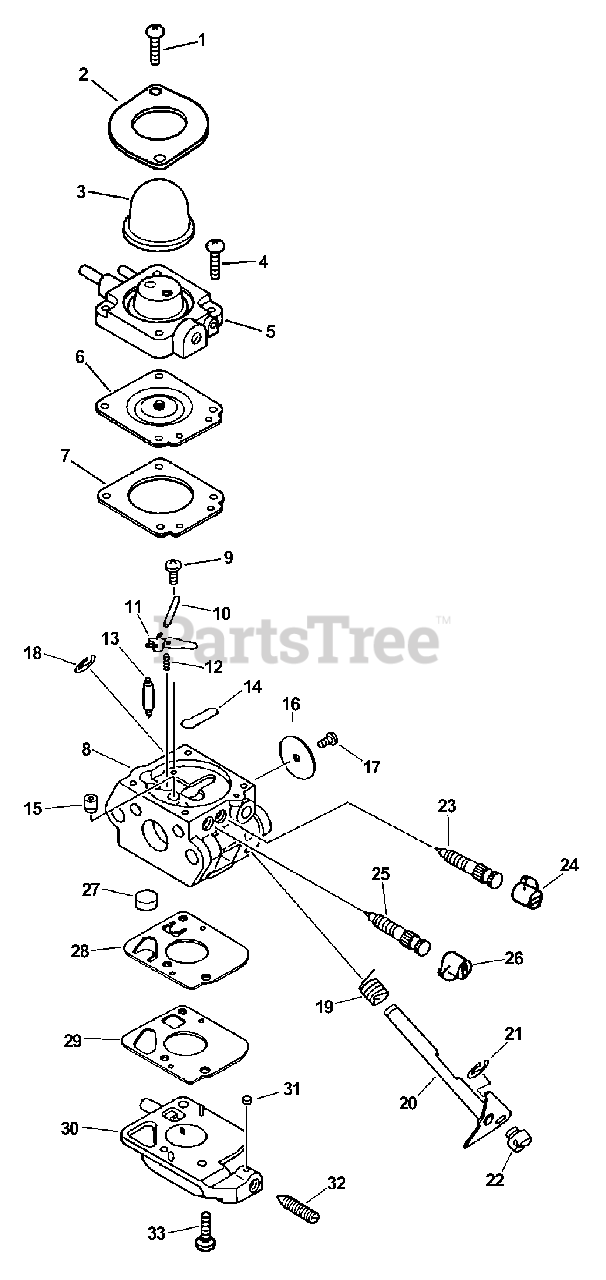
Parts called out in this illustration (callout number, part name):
1	SCREW, RETAINER
2	RETAINER, PURGE BULB
3	BULB, PURGE
4	SCREW, PURGE BASE
5	BASE, PURGE
6	DIAPHRAGM, METERING
7	GASKET, METERING
8	BODY, CARBURETOR
9	SCREW, METERING LEVER PIN
10	PIN, METERING LEVER
11	LEVER, METERING
12	SPRING, METERING LEVER
13	VALVE, INLET NEEDLE
14	PLUG, WELCH
15	NOZZLE, CHECK VALVE
16	VALVE, THROTTLE
18	RING, RETAINING
19	SPRING, RETURN
20	SHAFT, THROTTLE
21	RING, RETAINING
23	NEEDLE - LOW SPEED
24	CAP, LIMITER
25	NEEDLE - HIGH SPEED
26	CAP, LIMITER
27	STRAINER
28	DIAPHRAGM, PUMP
29	GASKET, PUMP
30	BASE, PURGE
31	PIECE, FRICTION
32	SCREW, IDLE ADJUST
33	SCREW, PUMP COVER
